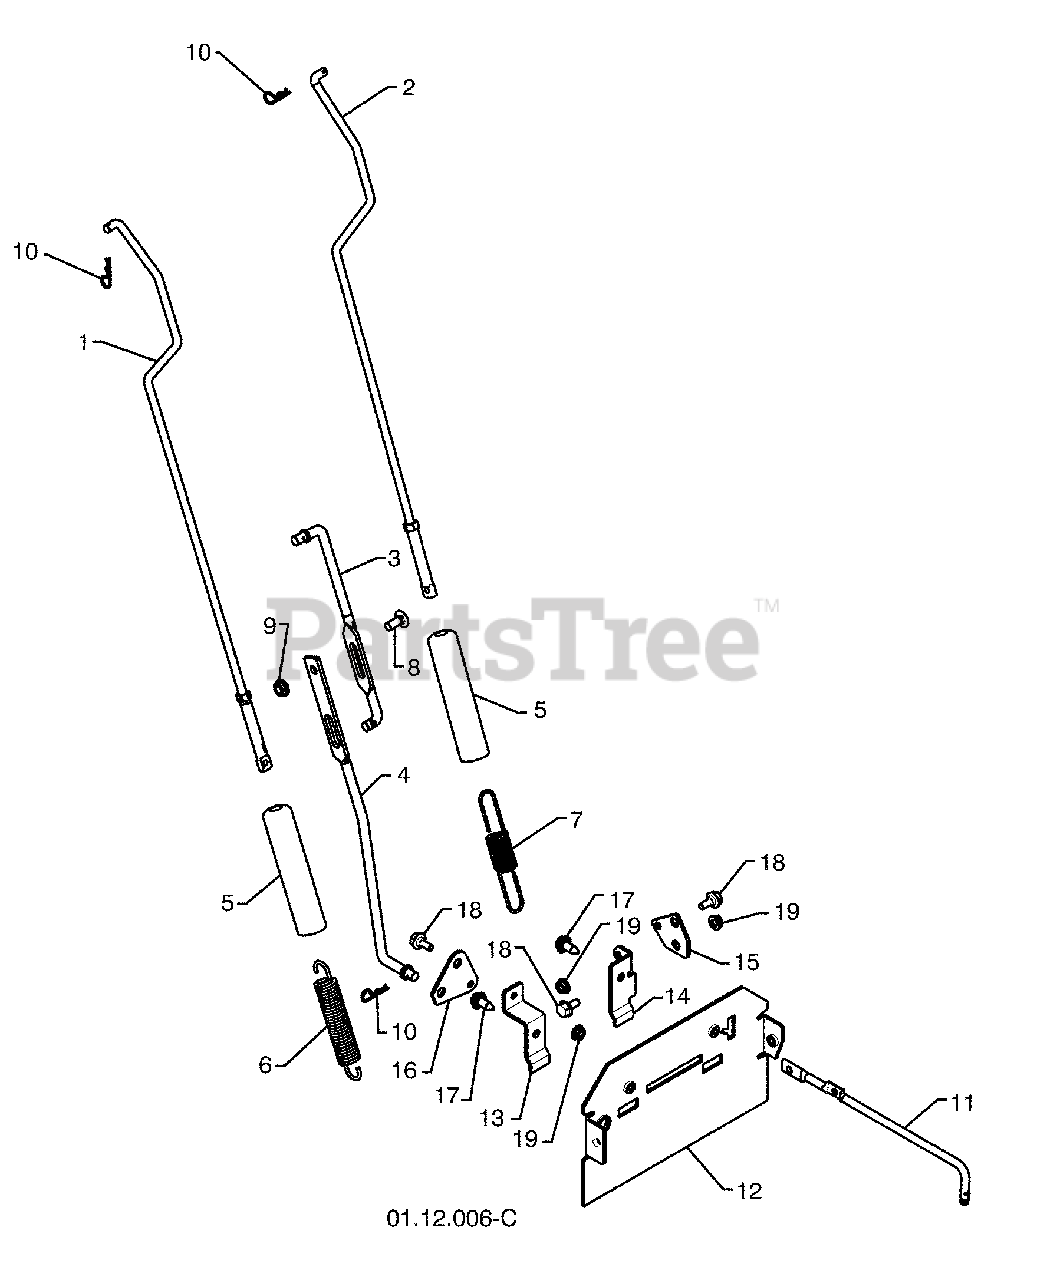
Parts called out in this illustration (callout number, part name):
1	IMPELLER ROD ASSEMBLY
2	TRACTION ROD ASSEMBLY
3	SHIFTER ROD TOP
4	SHIFTER ROD BOTTOM
5	SPRING SLEEVE
6	IMPELLER SPRING
7	TRACTION SPRING
8	CARRIAGE BOLT 5/16--18 X .750
9	NUT 5/16--18
11	CLUTCH ROD
12	REAR PLATE
13	SHIFTER PLATE BRACKET
14	CLUTCH PLATE BRACKET
15	CLUTCH PLATE
16	SHIFTER PLATE
17	BOLT 5/16--18 X .750
18	SHOULDER BOLT 1/4--20 X .500
19	Nut 1/4-20
